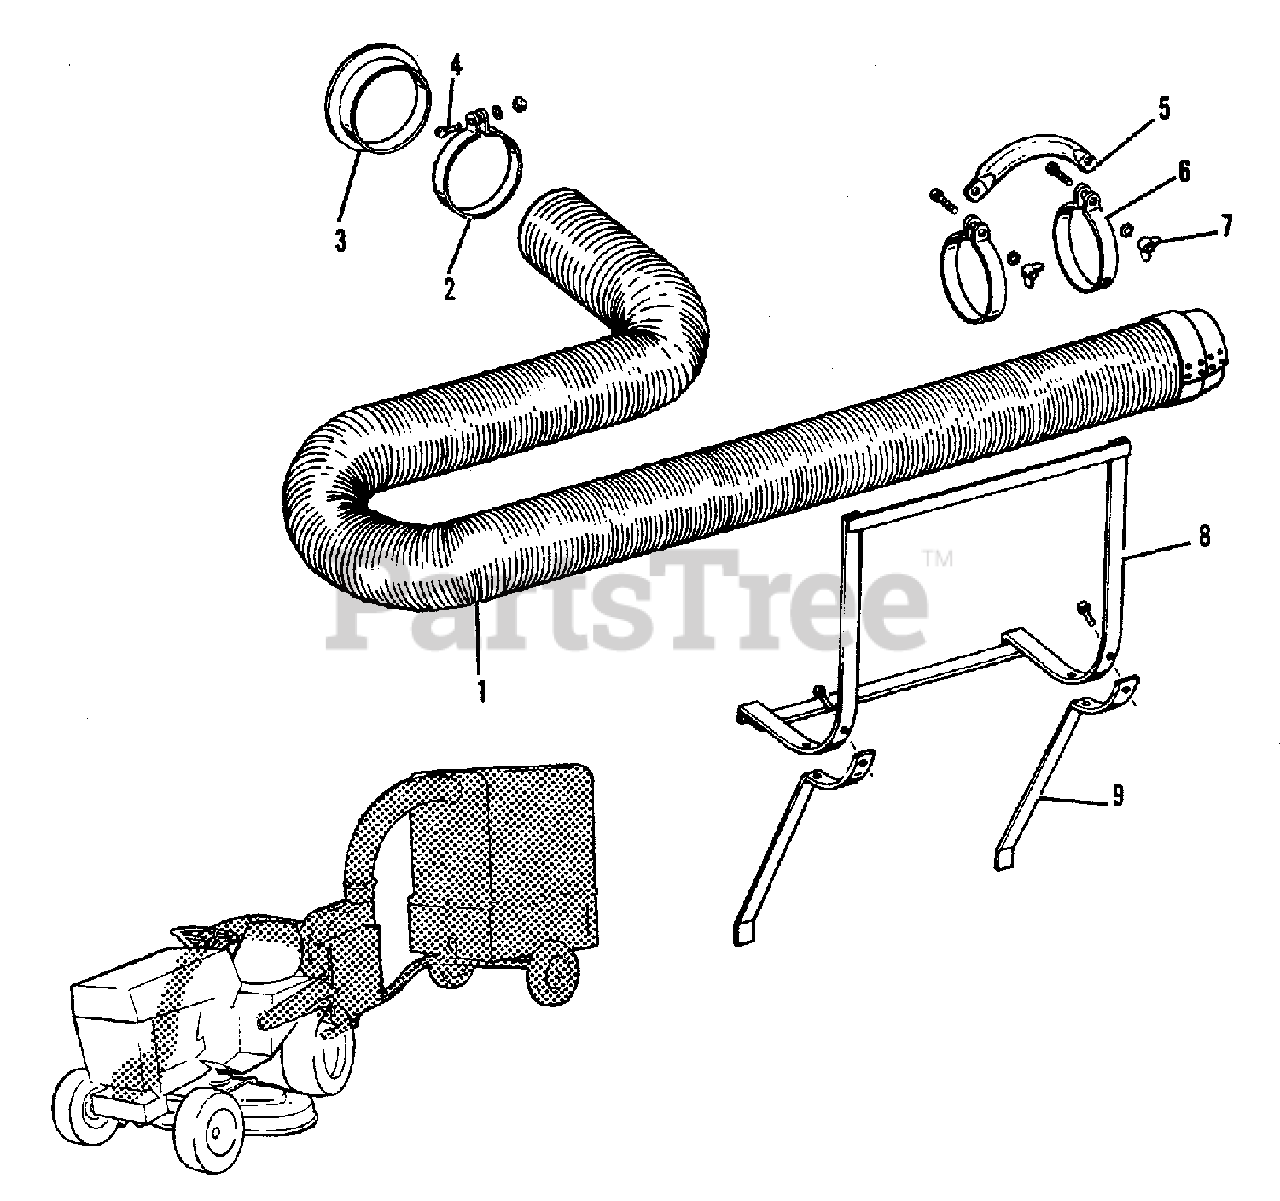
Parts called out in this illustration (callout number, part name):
1	HOSE ASSEMBLY
2	CLAMP, Hose
3	FLANGE, Hose
4	SCREW, Machine, Plated
4	LOCKWASHER, 1/4
4	NUT, 1/4NC
5	HANDLE, Hose
6	CLAMP, Hose Handle
6	CAPSCREW, 5/16NC x 3/4
6	LOCKWASHER, Plated, 5/16
7	NUT, Wing
8	CARRIER ASSEMBLY, Hose
8	CAPSCREW, 5/16NC x 7/8
8	WASHER, Plain, 5/16
8	LOCKWASHER, 5/16
8	NUT, 5/16NC
9	SUPPORT, Carrier
